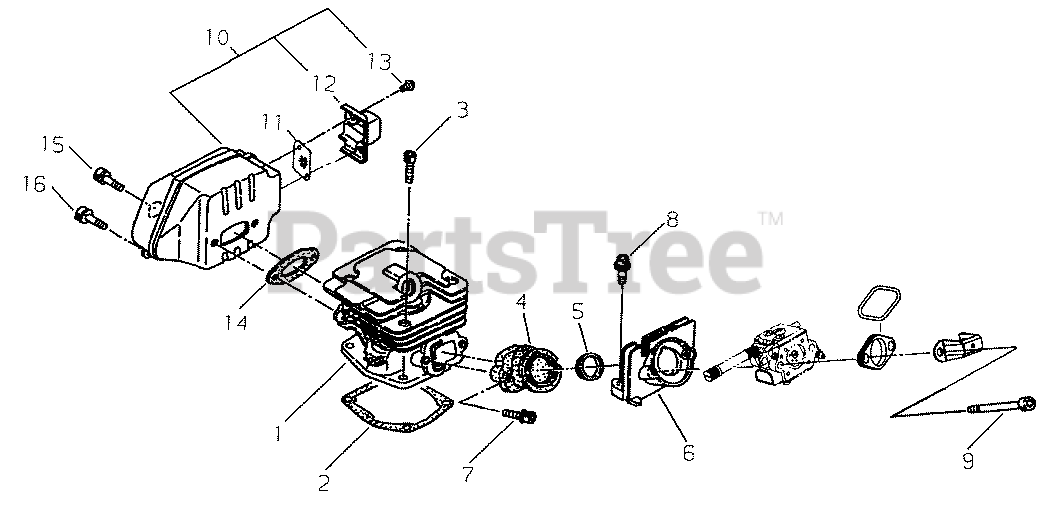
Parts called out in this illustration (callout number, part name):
2	GASKET, CYLINDER
4	BOOT
5	COLLAR 16
6	BRACKET
7	BOLT, ADHESIVE M4×12
8	BOLT, ADHESIVE M4×14
9	SCREW
10	MUFFLER ASSY
11	SCREEN, SPARK ARRESTER
12	GUIDE, EXHAUST
13	SCREW M4×6
14	GASKET, EXHAUST
15	BOLT M5×16
16	BOLT, ADHESIVE
